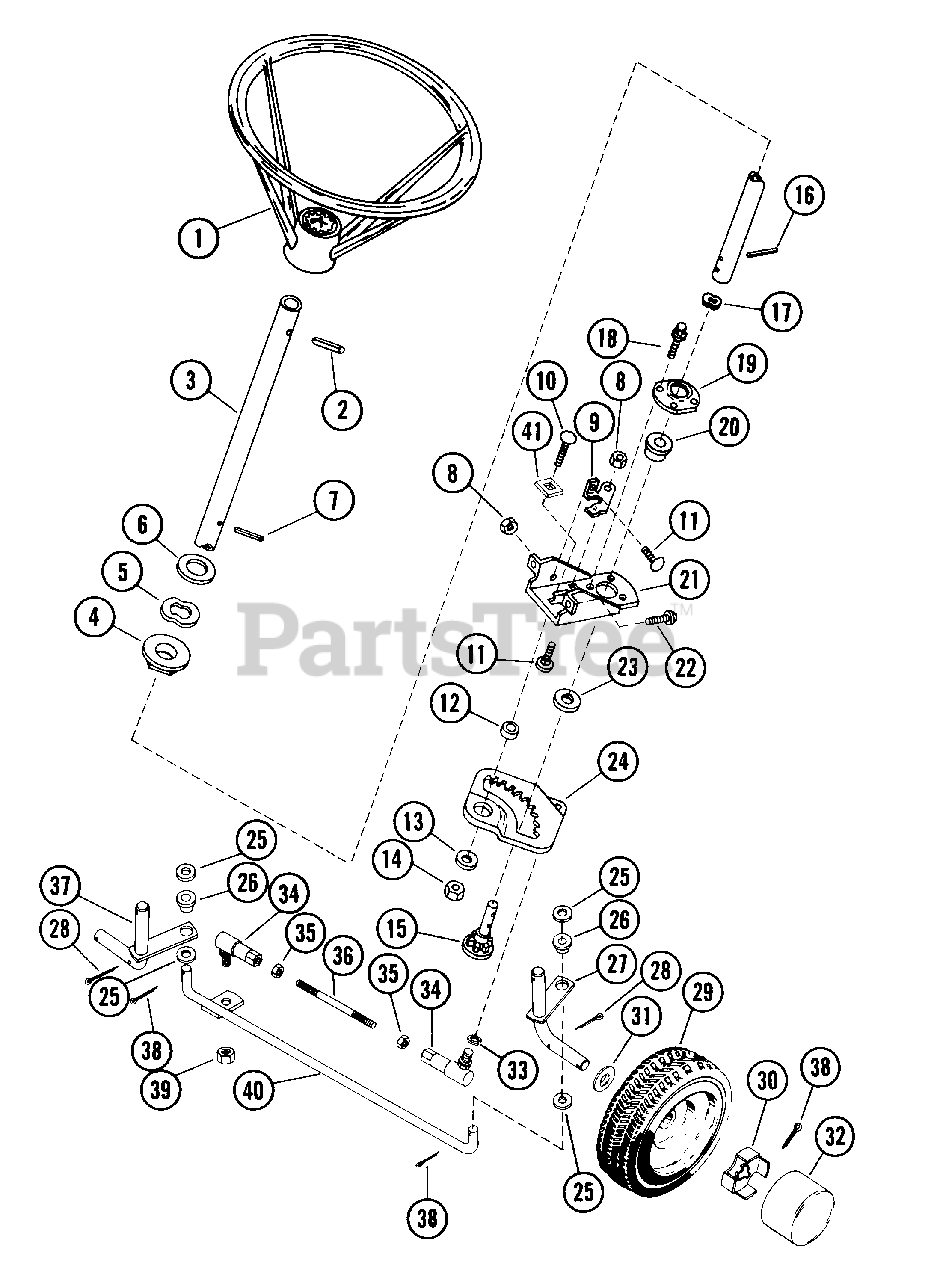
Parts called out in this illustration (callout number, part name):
1	STEERING WHEEL
2	PIN-ROLL .250X1.75
3	STEERING SHAFT
4	FLANGE BUSHING
5	SPRING WASHER
6	WSHR-FL-STL .755X1.375X.062 PL
7	PIN-ROLL .188X1.25
8	NUT-LK-CTR .250-20 PL
9	ADJUSTMENT BRACKET
10	BLT-RDHDSQSHNK .38-16X1.00 PL
11	BLT-RDHDSQNK .25-20X.62 PL
12	SPACER .380X.750X.236
13	WSHR-FL-STL .390X1.500X.125
14	NUT-LK-CTR .375-16 GR A PL
15	STEERING PINION
16	PIN-ROLL .188X1.00
17	WAVE WASHER .531X.781X.125FH
18	SCR-TAP 10-24X.25 CRSLPH PL 1A
19	RETAINING PLATE
20	BSHG-FLG .625X1.156X.375 SI
21	STEERING BRACKET
22	BLT-SERHFWH .31-18X.50 PL
23	WSHR-FL-STL .630X1.005X.062 PL
24	STEERING GEAR
25	WSHR-FL-STL .505X.875X.024 PL
26	BSHG-FLG.500X.625X.312X.750NY
27	L H WHEEL SPINDLE
28	PIN-COTR .12 X 1.25 PL
29	FRONT WHEEL ASSEMBLY
29	TIRE 4.10/3.50-4
29	WHL
29	ZERK FITTING
29	BSHG-FLG .750X1.380X.750X1.557
29	BRG-BALL .752X1.50X.50
30	SPINDLE CUP
31	SPINDLE WASHER
32	HUB CAP
33	WSHR-LK .375X.115 HVY PL
34	BALL JOINT
35	NUT .375-24 PL
36	STEERING LINK
37	R H WHEEL SPINDLE
38	PIN-COTR .12X1.0 PL
39	NUT-LK-CTR .375-24
40	TIE ROD
41	WASHER
